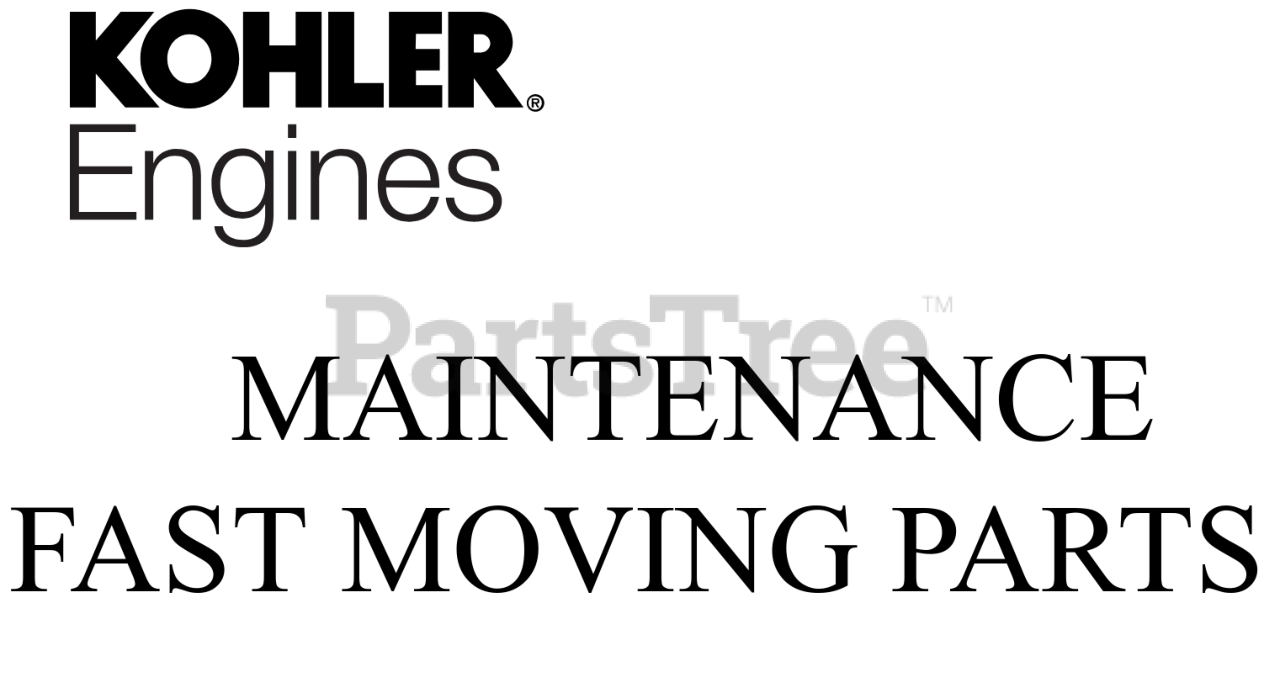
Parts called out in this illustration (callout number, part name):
NI	OIL FILTER
NI	ELEMENT, AIR FILTER
NI	ELEMENT, PRE-CLEANER
NI	MAINTENANCE KIT, 5400 SERIES
NI	PLUG, SPARK
